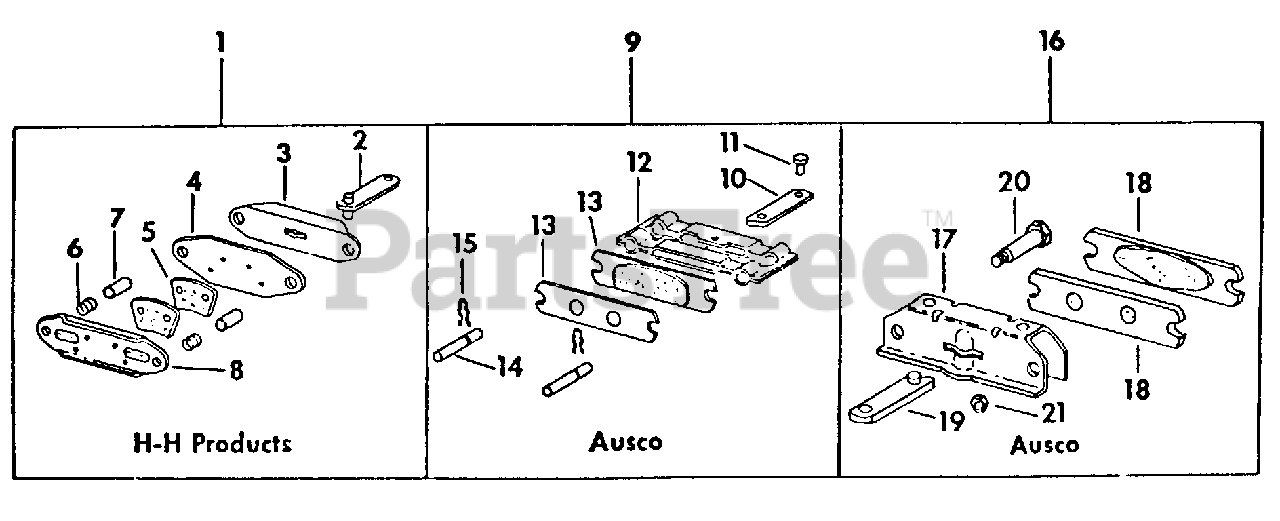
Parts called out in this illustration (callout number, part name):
1	Caliper Assy, Brake
2	Lever Assy, Cam
3	Plate, Actuator Cam
4	Carrier, Flat Plate
5	Liner, Brake
6	Spring, Compression
7	Spacer, Caliper
8	Carrier, Rib Plate
9	Caliper Assy, Brake LH
10	Lever, Actuator
11	Pin, 3/8 X 3/4 C-Z Rod End
12	Bracket, Secondary
13	Stator
14	Pin, Straight
15	Retainer, 3/8 Spring
16	Brake Assy, Spot LH
17	Bracket, Secondary
18	Stator
19	Lever, Actuating
20	Bolt, Shoulder
